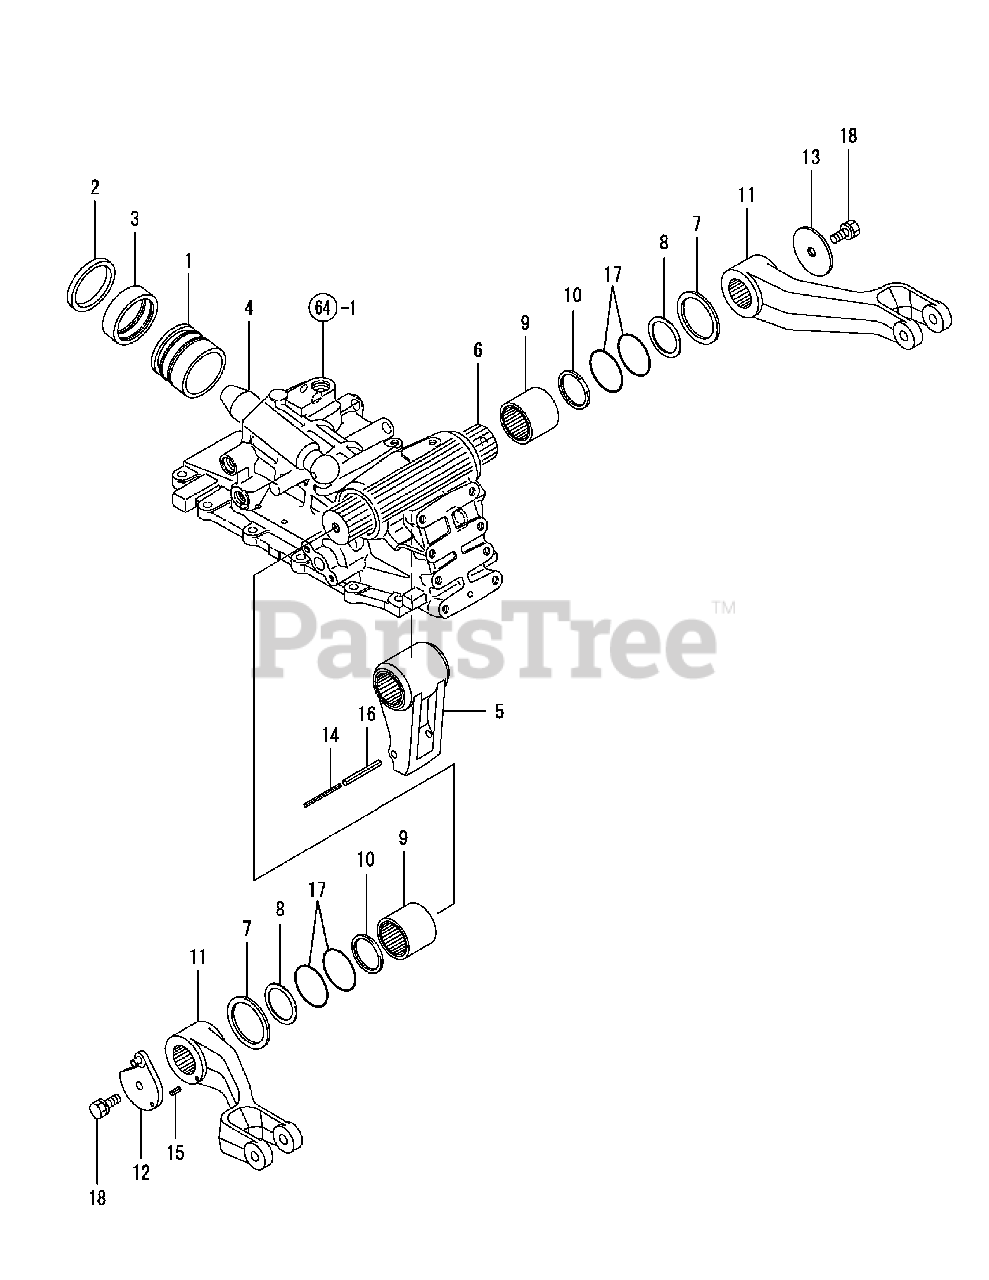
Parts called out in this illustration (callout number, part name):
7	WASHER, 65X82X2
9	SLEEVE, LIFT SHAFT
10	SEAL, SPLINE SHAFT
12	PLATE, P FEEDBACK
14	SPRING PIN 5X70
15	SPRING PIN 6X16
16	SPRING PIN 8X70
17	O-RING 1A G-65.0
